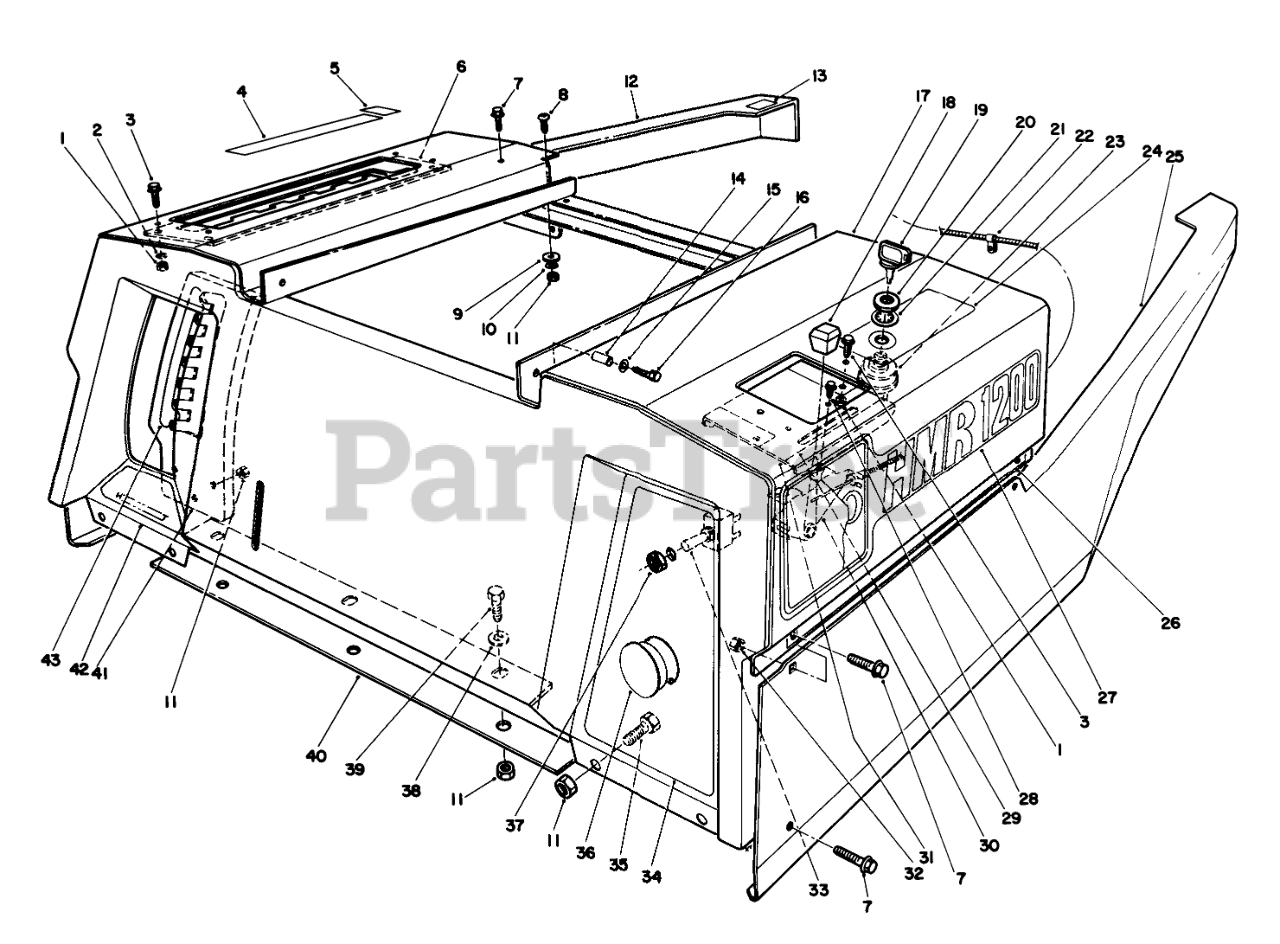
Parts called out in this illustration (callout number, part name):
1	NUT-LOCK, NI
2	WASHER-FLAT
3	SCREW-HHF
4	DECAL - SHIFT
5	DECAL - REVERSE
6	GATE-SHIFT B
7	SCREW-HHF
8	SCREW-HSBH
9	RUBBER WASHER
10	WASHER-FLAT
11	NUT-LOCK, NI
12	Fender-R.H. (Incl. Ref. #13)
13	DECAL-SURFACE, HOT
14	SPACER
15	WASHER-FLAT
16	SCREW-HH
17	Body (Incl. Ref. #8-11, 24, 26, 27, 34 & 42)
19	KEY-IGNITION
20	NUT-HH
21	WASHER-TOOTH, INTERNAL
22	CLIP-CLOSED, INSULATED
23	Switch-Starter (Incl. Ref. #20 & 21)
24	DECAL - IGNITION
25	LH FENDER WA R
26	DECAL - STEERING (L)
27	DECAL - 1200
28	SCREW-HWHTF
29	DECAL - THROTTLE
30	CHOKAMATIC CONTROL
31	CONTROL PLATE B
33	Switch (Incl. Ref. #37)
34	DECAL - DECK SWITCH
35	SCREW-HH
36	DOME PLUG
37	NUT
38	WASHER-PLAIN
39	SCREW-HH
40	FLOOR PAN GASKET
41	HOC QUADRANT B
42	DECAL - HEIGHT OF CUT
43	DECAL - HOC
